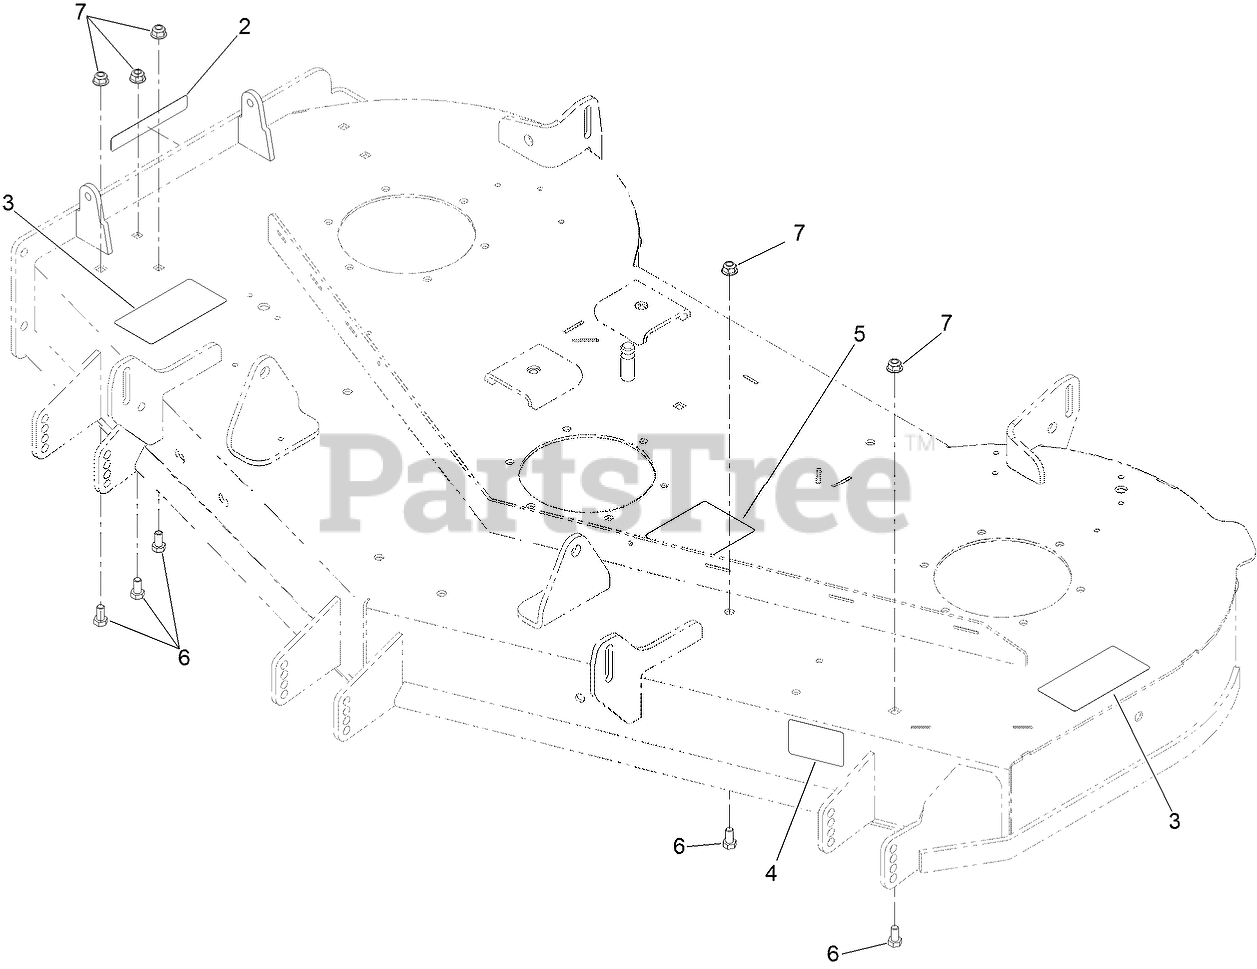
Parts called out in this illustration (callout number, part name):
2	DECAL-DANGER
3	DECAL-DANGER, DECK
4	DECAL-SCALP, ANTI
5	DECAL-ROUTING, BELT
6	SCREW-HH
7	NUT-HF, NI
